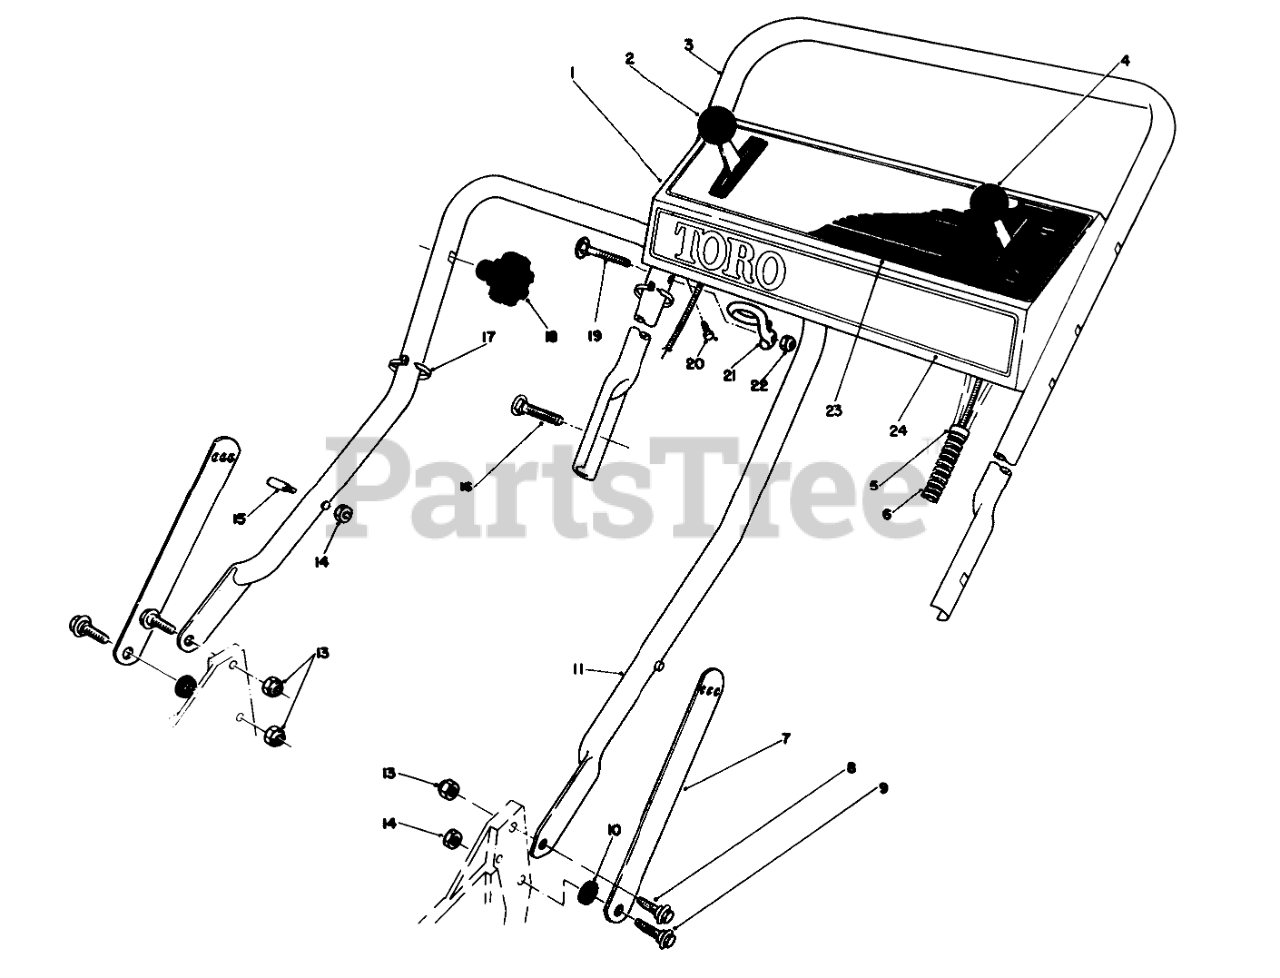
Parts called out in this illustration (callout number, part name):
1	Panel-Control
2	GROUND SPEED CONTROL
3	UPPER HANDLE
4	THROTTLE CONTROL
5	FITTING-RING
6	CONTROL CABLE COVER
7	Handle Latch
8	SCREW-SHOULDER
9	SCREW-SHOULDER
10	SPACER
11	LOWER HANDLE ASM
13	NUT-LOCK, NI
14	NUT-LOCK, NI
15	HANDLE PIN
16	5/16-18 X 2 HNDLE SCREW
17	TIE-CABLE
19	HANDLE SCREW
20	SCREW-HWHTF
21	Guide
22	NUT-LOCK, NI
23	Decal-Instructions
24	Decal-Toro
